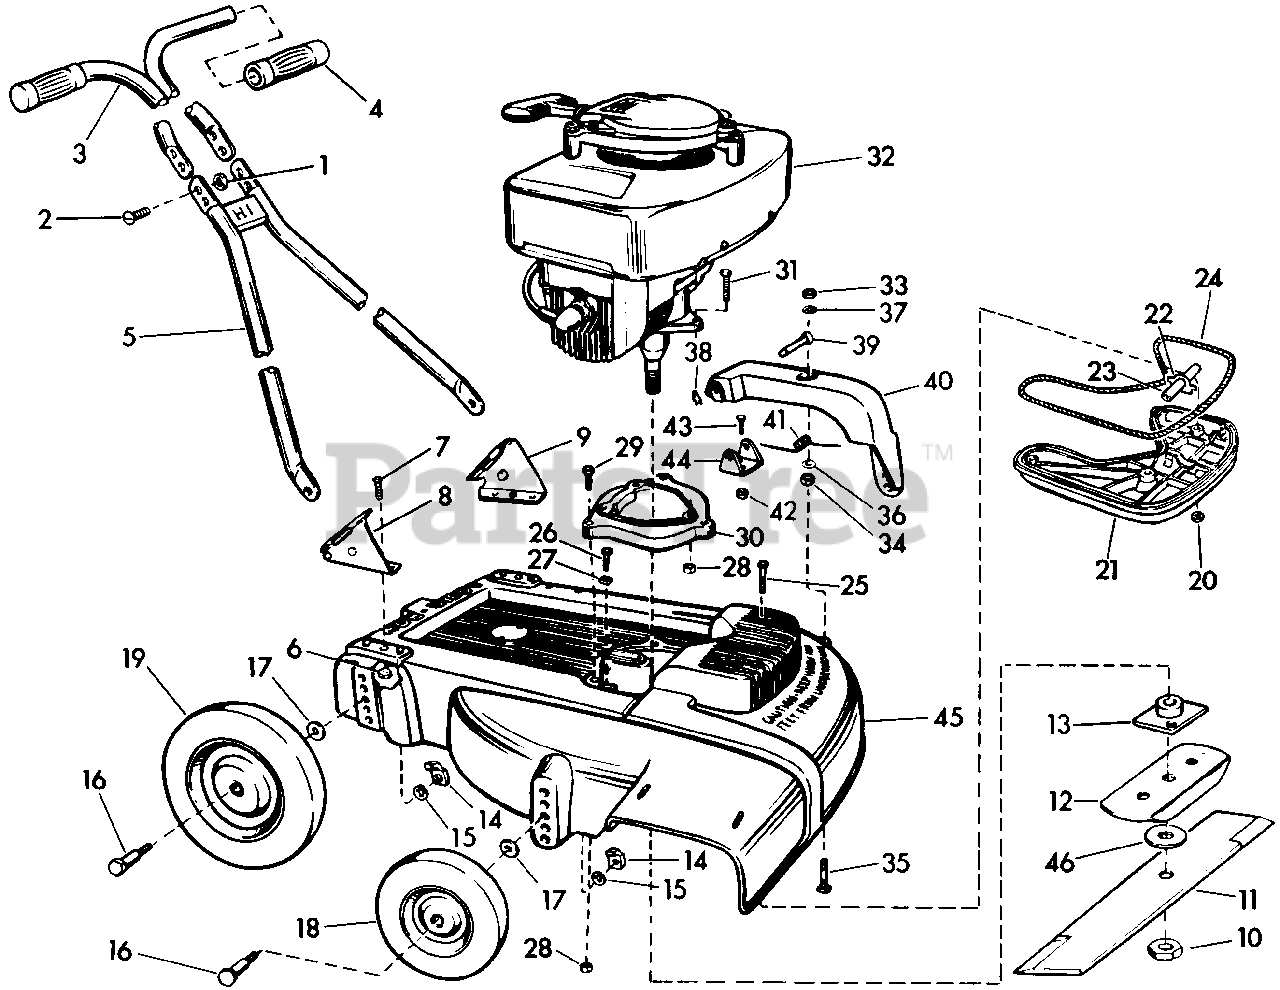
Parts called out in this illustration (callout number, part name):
1	Nut-Handle
2	Screw-Handle
3	Handle Assembly-Top
4	Grip-Handle
5	Handle Assembly-Bottom
6	Nut-Handle Bracket
7	Screw-Handle Bracket
8	Bracket-Handle, Right
9	Bracket-Handle, Left
10	Nut-Blade
11	Blade-18"
11	Blade-21"
12	Stiffener-Blade
13	Collar and Plate Assembly
14	Nut-Wheel
15	Washer-Lock, Wheel
16	Bolt-Shoulder, Wheel
17	Washer-Plain
18	Wheel Assembly, 6 x 1.50
19	Wheel Assembly, 8 x 1.75
20	Nut-Muffler
21	Muffler
22	Gasket-Internal, Tube
23	Tube-Internal, Muffler
24	Gasket-Muffler
25	Bolt-Muffler, Long
26	Bolt-Muffler, Short
27	Gasket-Muffler Bolt
28	Nut-Nylok, Sub Base and Engine Mounting
29	Screw-Sub Base Mounting
30	Sub Base
31	Bolt-Engine Mounting
32	Engine-Model C-14
33	Nut-Nylok, Level-Ride Shoulder Bolt
34	Nut-Level-Ride Bolt
35	Bolt-Level-Ride Arm
36	Washer-Level-Ride Arm
37	Washer-Level-Ride Arm, Fiber
38	Pin-Hair, Level-Ride Arm
39	Pin-Level-Ride Arm Brkt.
40	Arm-Level-Ride
41	Spring-Level-Ride Arm
42	Nut-Nylok, Level-Ride Bracket
43	Screw-Level-Ride Arm Bracket
44	Level-Ride Arm Bracket
45	Housing-18" Model 5210
45	Housing-21" Model 7210
46	Washer-Fiber (21" only)
